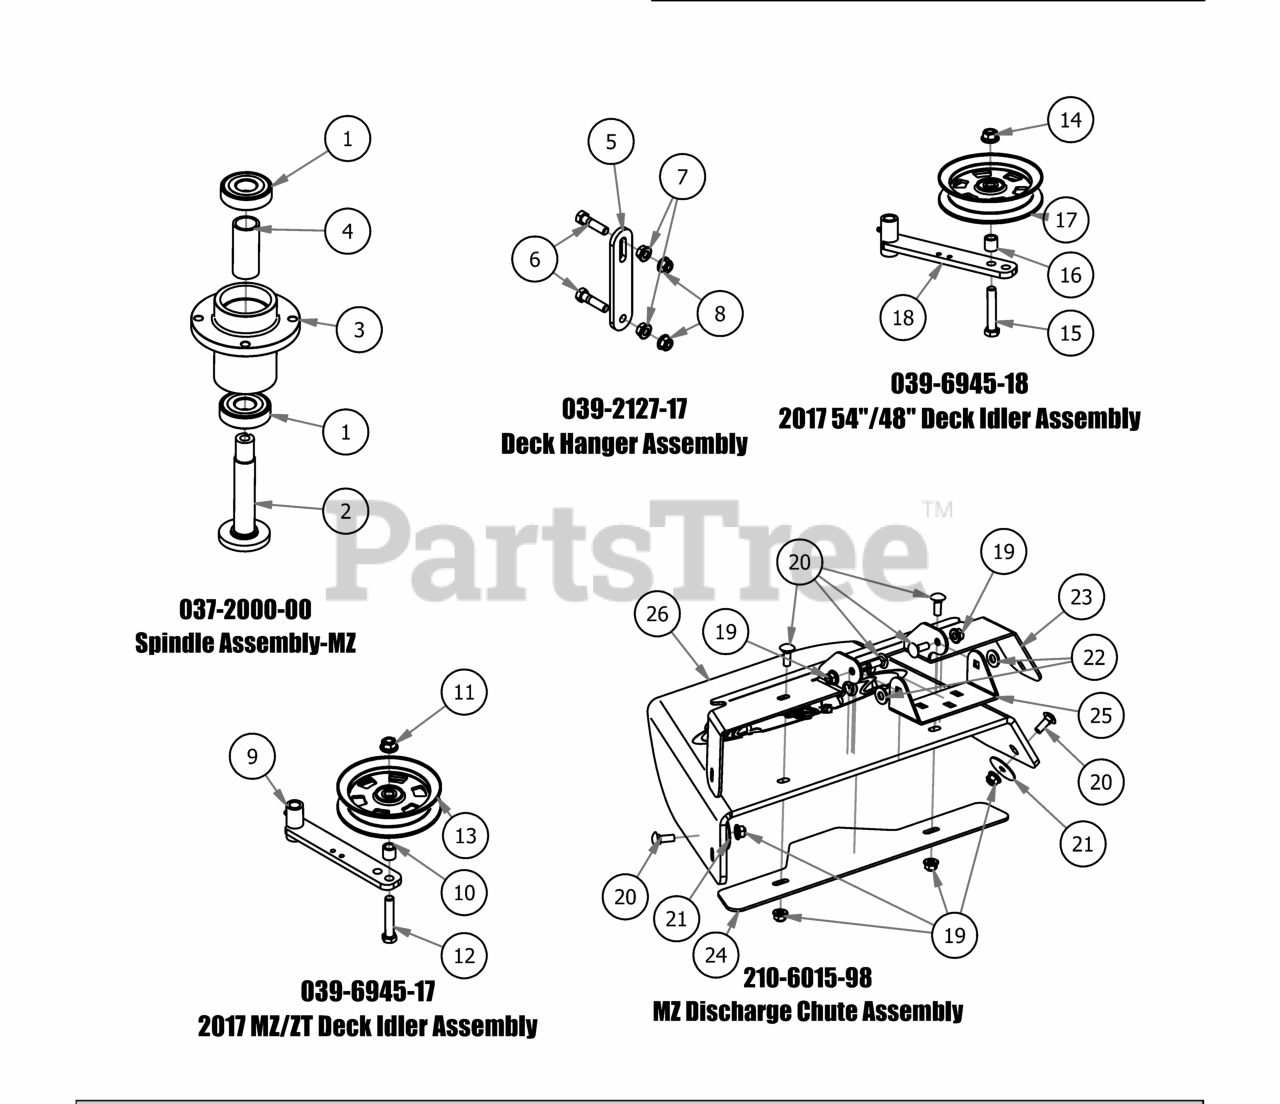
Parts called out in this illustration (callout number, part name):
1	Spindle Bearing
2	Spindle Shaft
3	Spindle Housing
4	Spindle Spacer-Component
5	2017 MZ/ZT Deck Hanger
6	3/8" x 1 1/2" Hex Bolt
7	3/8" Flange Nut
8	3/8" Nylock Flange Nut
9	Deck Idler
10	.51 ID X .75 OD X .75 LGTH SOLID SPACER ZINC
11	1/2-13 NYLON INSERT FLANGE LOCKNUT ZINC
12	1/2-13 X 2-3/4 HEX CAP SCREW (GR.5) ZINC
13	5" Idler Pully
14	1/2-13 NYLON INSERT FLANGE LOCKNUT ZINC
15	1/2-13 X 2-3/4 HEX CAP SCREW (GR.5) ZINC
16	.51 ID X .75 OD X .75 LGTH SOLID SPACER ZINC
17	5" Idler Pully
18	Deck Idler
19	5/16" Nylon Flange Nut
20	5/16" x 7/8" Carriage Bolt
21	5/16 Fender Washer
22	.360 ID Plastic Washer
23	Discharge Chute Bracket 48 MZ (Upper)
24	2017 MZ Discharge Chute Bracket-Lower
25	Chute Hanger 48 MZ
26	Rubber Discharge Chute MZ (Component)
